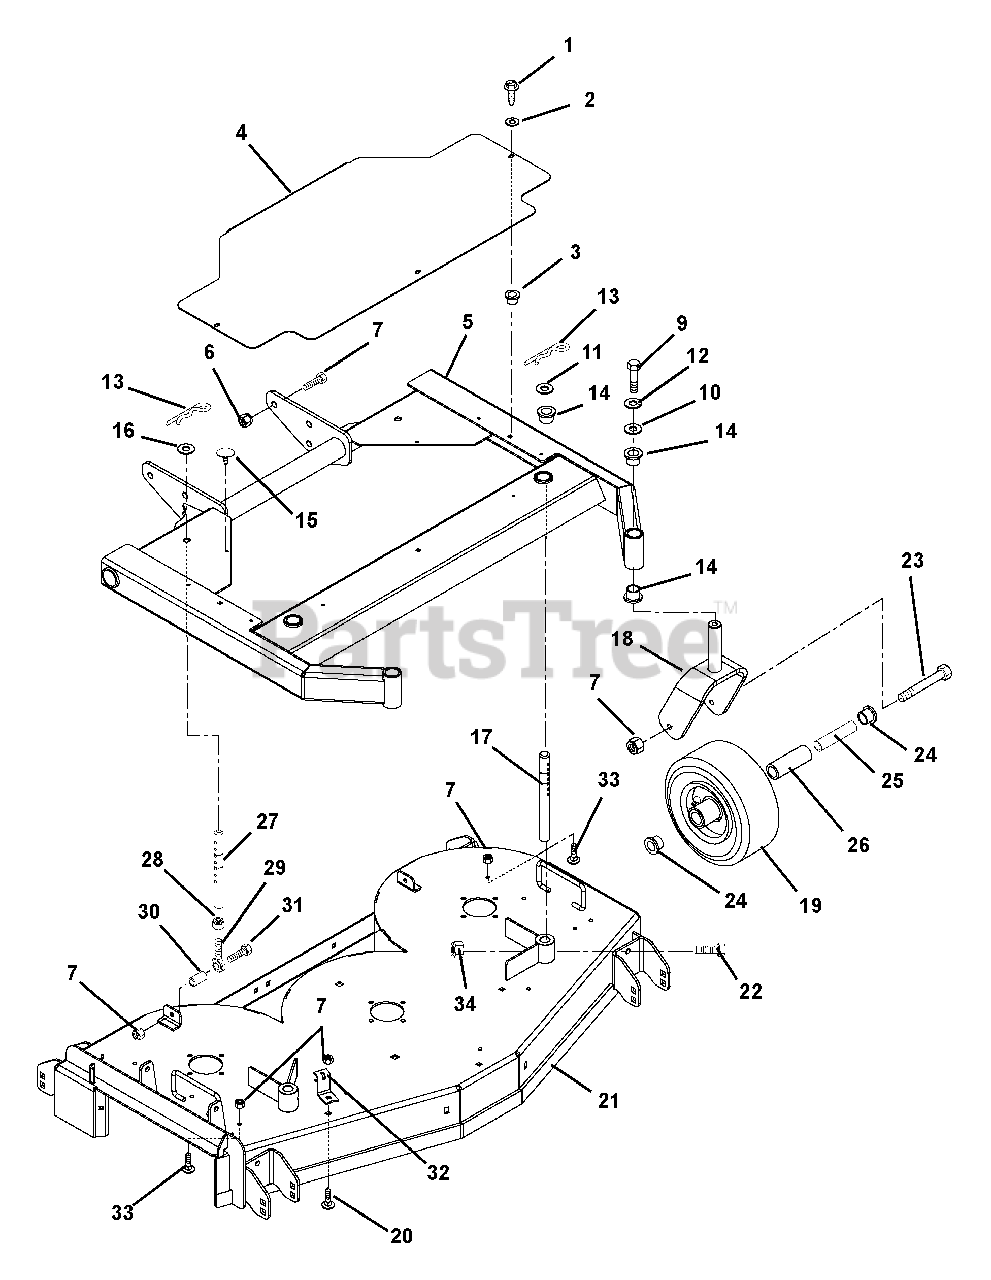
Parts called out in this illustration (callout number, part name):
1	@SCR-TAP .25-20X.50 HWH TR YWZ
2	@WSHR-FL-STL.281X.62X.065 YWZC
3	GRMT,PLASTIC
4	COVER- BELT PRO 48 FLOATING
5	WMT-MOWER FRAME- 48" FLOAT
6	@NUT-LK-NYL .625-11 YWZC
7	@BLT-HEX .62-11X1.50 GR5 YWZC
8	@NUT-LK-TOP-FLG .38-16 YWZC
9	@BLT-HEX .38-16X1.25 GR5 YWZC
10	WSHR-FL-STL .380X1.50X.125YWZC
11	WSHR-FL-STL .890X1.500X.1196YZ
12	@WSHR-LK .38X.094 REG YWZC
13	PIN-HAIR-INT .17X.68X3.50 YWZC
14	BSHG-FLG 1.00X1.25X1.50X1.50EP
15	BUMPER GROMMET
16	@WSHR-FL-STL.688X1.75X.134 YWZ
17	ROD- FRONT HEIGHT ADJUSTMENT
18	WMT - CASTER FORK
19	WHEEL 9 X 3.50 SEMI-PNEUMATIC
20	@BLT-RDHDSQNK .38-16X.75 G5YZ
21	KIT-48" FL MOWER DECK W/DECALS
22	@BLT-HEX .25-20X2.00 GR5 YWZC
23	BLT-HEX .38-16X5.50 YWZC
24	RTNR-BEARING-PRO
25	BEARING .625 X .380 X 4.08
26	BEARING, ROLLER--PRO
27	ROD- REAR HEIGHT ADJUSTMENT
28	NUT-JAM .375-24 YWZC
29	ROD END, 3/8 RH
30	BSHG-SLV .377X.624X.370
31	@BLT-HEX .38-16X1.50 GR5 YWZC
32	ANCHOR, SPRING (RED)
33	@BLT-RDHDSQNK .38-16X.75 G5YZ
34	@NUT-LK-TOP-FLG .25-20 YWZC
